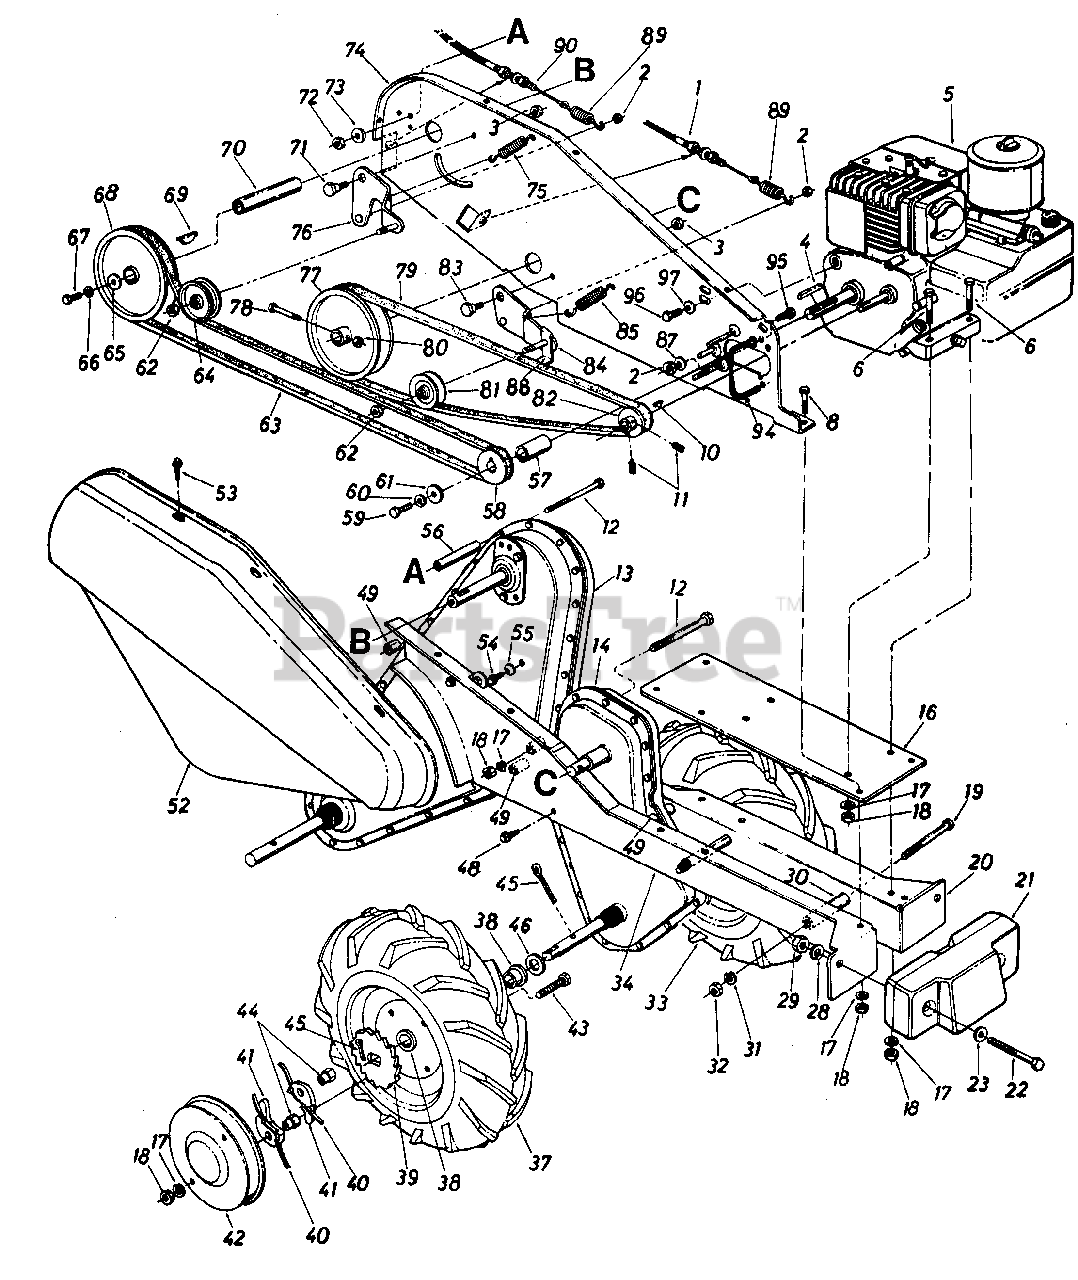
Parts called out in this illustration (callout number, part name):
1	Clutch Control Cable
2	Hex Cent. L-Nut 1/4-20 Thd.
3	Hex Cent. L-Nut 3/8-16 Thd.*
4	Sq. Key 3/16" Dia. x .75
5	Engine
6	Hex Bolt 5/16-18 x 1.50" Lg.*
8	Hex Bolt 5/16-18 x .75" Lg.*
10	Hi-Pro Key #5 Woodruff
11	Set Scr. 1/4-28 x .25" Lg.
12	Hex Bolt 5/16-18 x 3.0" Lg.*
18	Hex Nut 5/16-18 Thd.*
19	Hex Bolt 3/8-24 x 3.0" Lg.*
22	Hex Bolt 1/2-13 X 4.0" Lg.*
23	Fl-Wash. 1/2" I.D. x 1.0" O.D.
28	L-Wash. 1/2" I.D.*
29	Hex Nut 1/2-13 Thd.*
30	Spacer 3/8" I.D. x 5/8" O.D. x 2.18" Lg.
31	L-Wash. 3/8" I.D.*
32	Hex Nut 3/8-24 Thd.*
33	Comp. Wheel Ass'y. L.H.
38	Flange Brg. 7/8" I.D. x 1.12" Lg.
39	Ratchet Wheel
40	Nylon Spring
41	Pawl .44" I.D.
42	Wheel Cover
43	Hex Bolt 5/16-18 x 1.25" Lg.*
44	Special Hex Nut 5/16-24 Thd.
45	Cotter Pin 1/8" Dia. x 1.25" Lg.*
46	Fl-Wash. 7/8" I.D. x 1-3/8" O.D. x .06
48	Hex Wash. Self-Tap Scr. 5/16-24 x .50" Lg.
49	Spacer 5/16" I.D. x 16 Ga. x.96" Lg.
52	Belt Cover
53	Hex Wash. S-Tap Scr. 1/4-20 x.50" Lg.
54	Hex Wash. S-Tap Scr. 1/4-20 x.3/8" Lg
55	Bell Wash. 1/4" I.D.
56	Spacer 3/8" I.D. x 1/2" O.D. x 2.0" Lg.
57	Spacer 314" I.D. x 1.12" O.D. x 1.56" Lg.
58	1/2" "V"-4L Pulley 3/4" I.D. x2.59" O.D.
59	Hex Bolt 3/8-24 x 1.00" Lg.
60	L-Wash. 3/8" I.D.*
61	Fl-Wash. 3/8" I.D. x 1.25" O.D.
62	Hex L-Nut 3/8-24 Thd.
63	V-Belt 1/2" X 54" Lg.
64	Fl-ldler Pulley 3.75" O.D. x 3/8" I.D.
65	Fl-Wash. .25" I.D. x .93" O.D. x .1 20
66	L-Wash. 1/4" I.D.*
67	Hex Bolt 1/4-28 x .75" Lg.*
68	Split Pulley 6" Dia. x 5/8" I. D.
69	Hi-Pro Key
70	Spacer
71	Shld. Bolt 1/2" Dia. x .210" Lg.
72	Hex Nut 5/16-18 Thd.*
73	L-Wash. 5/16" I.D.*
74	Side Plate Ass'y.
75	Ext. Spring .50" O.D. x 1.55" Lg.
76	Idler Bracket Ass'y. Tines
77	Pulley 6" Dia. x 5/8" I.D.
78	Hex Bolt 1/4-28 x 1.50" Lg.*
79	V-Belt 1/2" X 42" Lg.
80	Hex Cent. L-Nut 1/4-28 Thd.*
81	V-ldler Pulley 2-5/8" O.D.
82	1/2" "V"-Pulley 2-1/4" O.D. x .50" I.D.
83	Shld. Bolt 1/2" Dia. x .160" Lg.
84	Idler Bracket Ass'y Wheels
85	Ext. Spring .50" O.D. x 1.97" Lg.
85	Hex Nut 1/4-20 Thd.*
87	Bell-Wash. 1/4" I.D.
88	Belt Keeper Ass'y.
89	Ext. Spring
90	Clutch Control Cable
94	Belt Keeper
95	Hex Bolt 1/4-20 x 1.25" Lg.*
96	Hex Bolt 5/16-24 x .62" Lg.*
97	Bell-Wash. 5/16" I.D.
